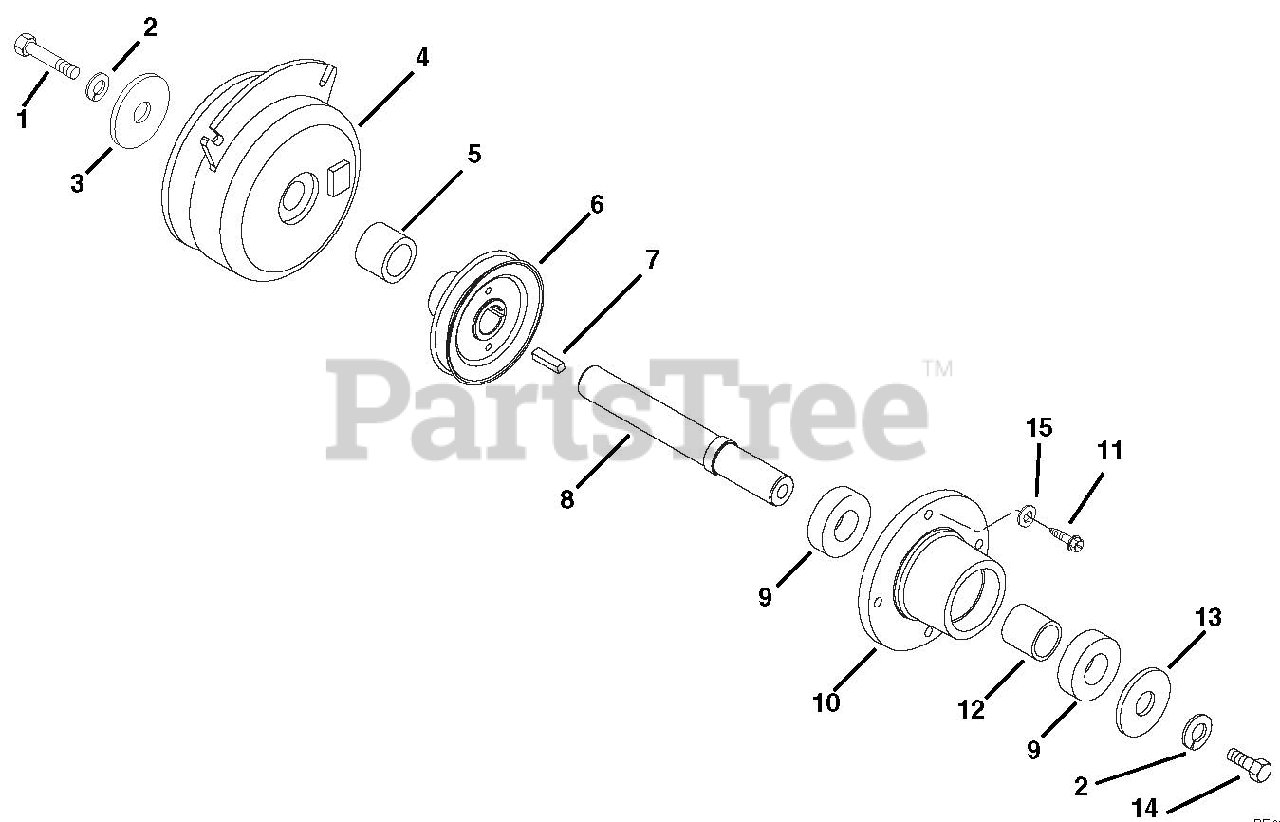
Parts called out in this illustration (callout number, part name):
1	BLT-HEX .44-20X1.50 GR5 YWZC
1	BLT-HEX .44-20X2.50 GR5 YWZC
2	@WSHR-LK .44X.109 REG YWZC
3	WSHR-FL-STL .469X2.00X.25 YWZC
4	CLUTCH, ELECTRIC - WARNER
4	ELECTRIC CLUTCH/BRAKE (3.4AMP)
5	SPACER 1.004X1.500X.740
6	SHEAVE, JACKSHAFT 4.50
7	KEY-SQ .25X1.0X.25 SAE 8630
7	KEY-SQ .25X.625X.25 SAE 8630
8	SHAFT - JACK
9	BRG-BALL .984X2.04X.59
10	HOUSING, TRANS SPNDL, BLACK
11	@SCR-TAP .31-18X.75 HWH TR YWZ
12	SPACER 1.0X1.253X1.26
13	WSHR-FL-STL.463X1.375X.25 YWZC
14	BLT-HEX .44-20X1.00 GR5 YWZC
15	WSHR-FL-STL .328X1.0X.094 YWZC
